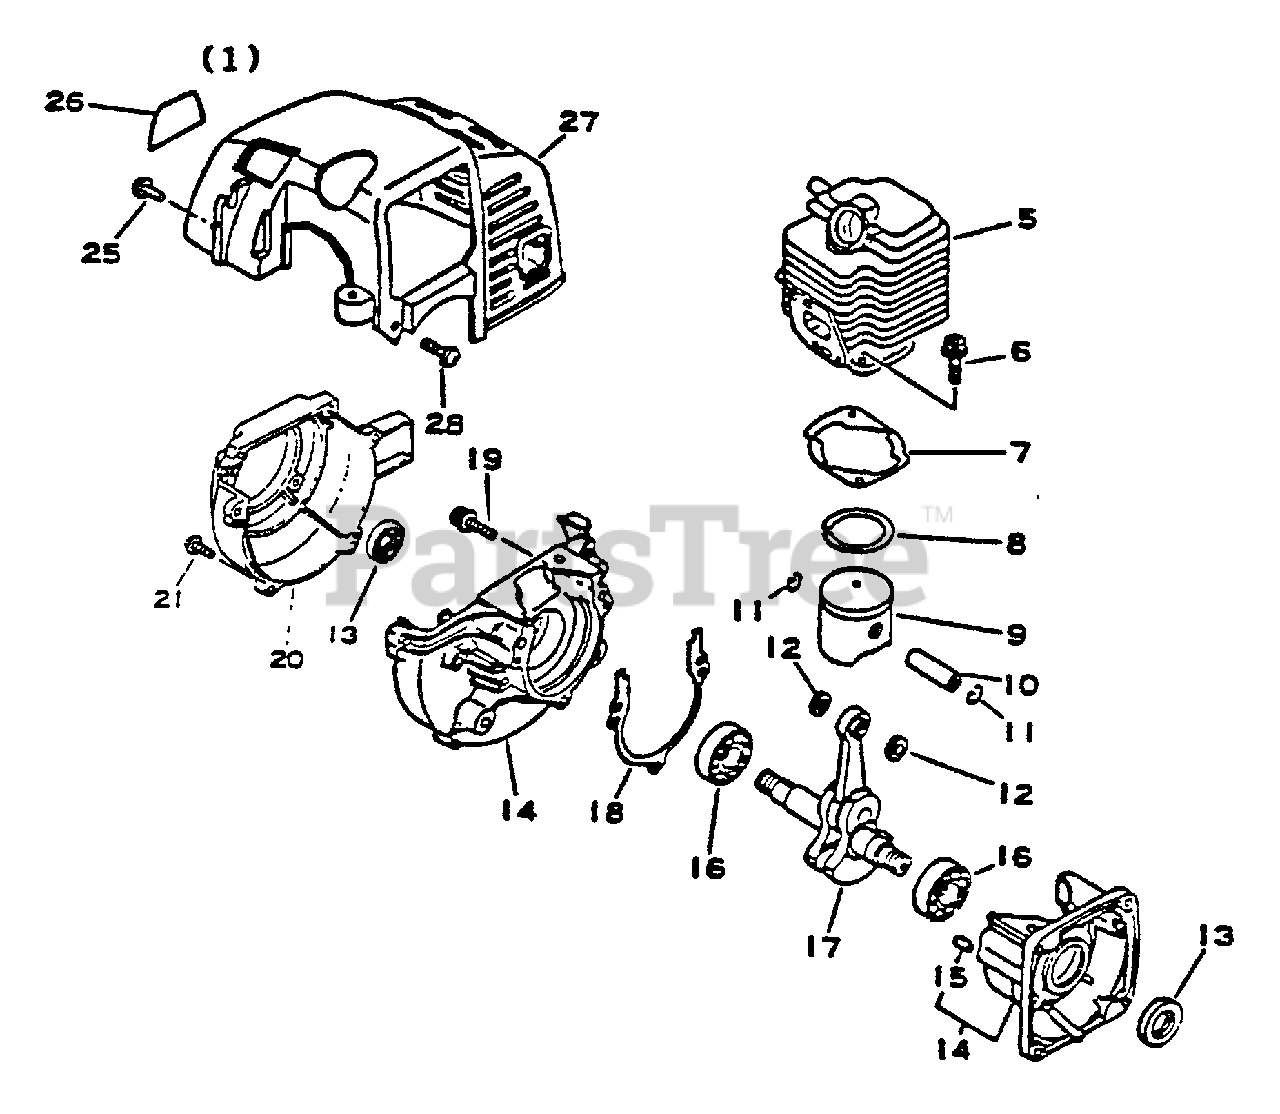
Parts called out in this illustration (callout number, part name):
5	CYLINDER
6	BOLT 5×22
7	GASKET, CYLINDER
8	RING, PISTON
9	PISTON
10	PIN, PISTON 8
11	RING, SNAP
12	WASHER, THRUST
13	SEAL, OIL 12
14	CRANKCASE KIT
15	PIN, LOCATING 4
16	BEARING, BALL - 6201 C3
17	CRANKSHAFT ASSY
18	GASKET, CRANKCASE
19	SCREW 5×25
20	COVER, FAN - ORANGE
21	SCREW 4×16
25	SCREW 4×12
27	COVER, ENGINE
28	SCREW 4×16
